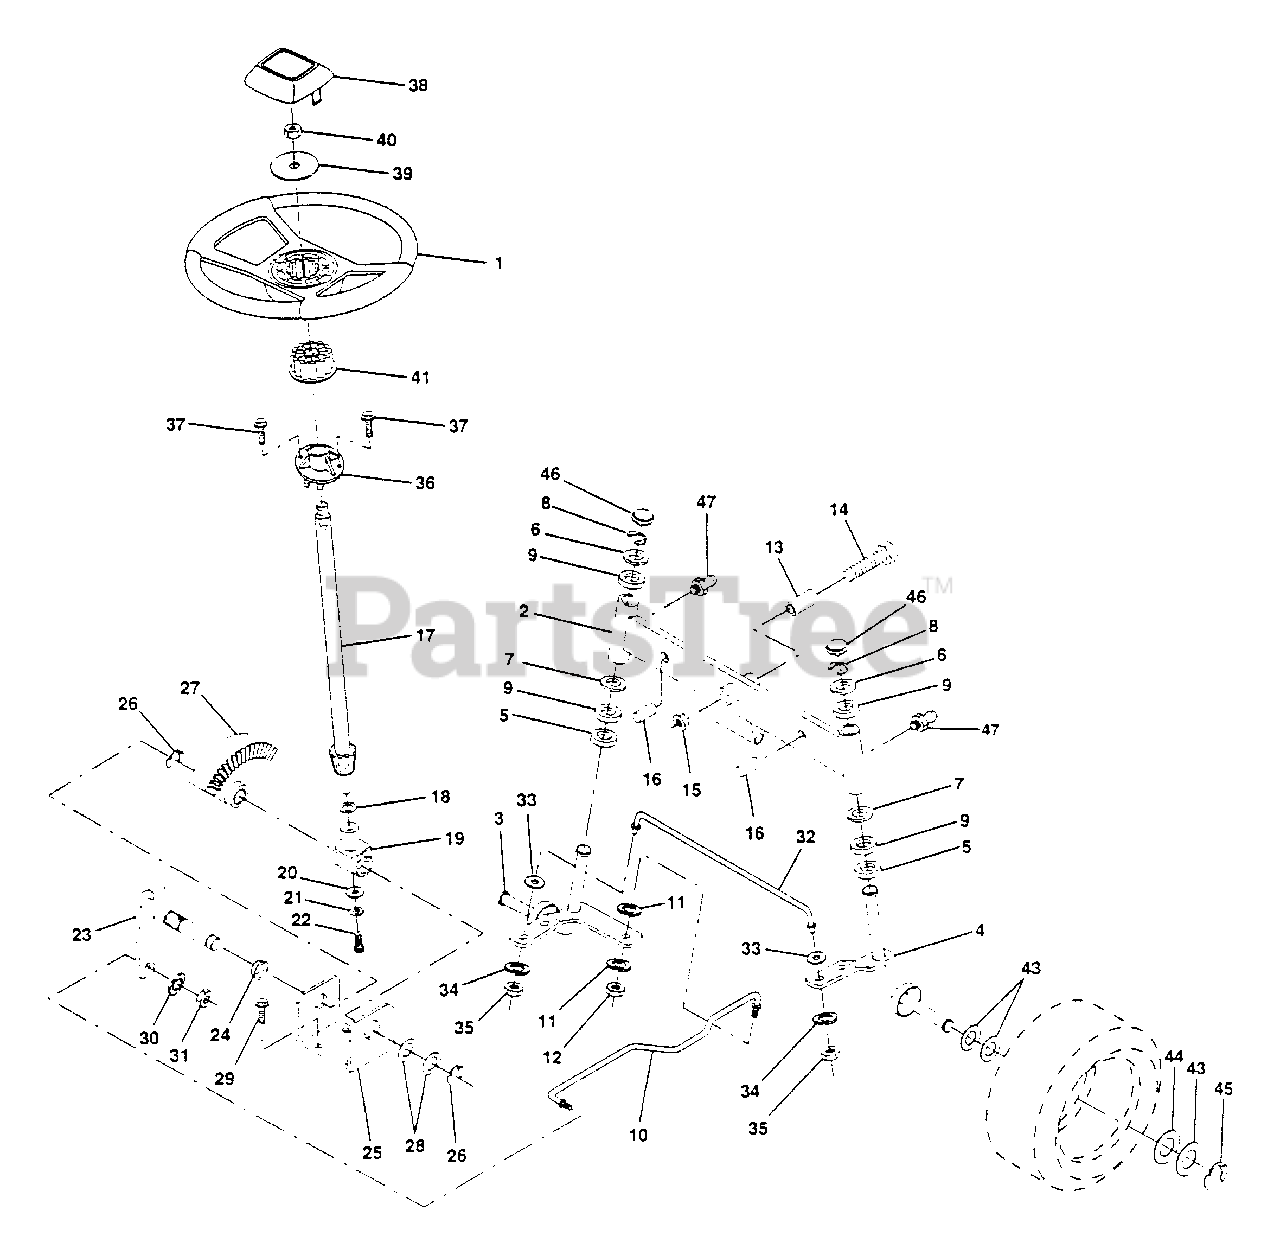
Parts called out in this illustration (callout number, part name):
1	Wheel Steering
2	Axle Asm Fr LT W/gzks 38/42
3	Spindle Asm LH
4	Spingle Asm RH
5	Bearing Race Thrust Harden
6	Washer 25/32 X 1-5/8 X 16 Ga
7	Washer 27/32 X 1-1/4 X 16 Ga
8	Ring Klip #t5304-75
9	Bearing Col Strg
10	Link Drag Sol Ball Jt
11	Washer Lock Hvy Hlcl Spr 3/8
12	Nut Fin 3/8-24 Unf
13	Spacer Bearing Axle Front
14	Bolt Hex 5/8-11 Unc X 3-1/2
15	Nut Lock Flange 5/8-11 Unc
16	Pin Axle 5/8 X 1 55/1 54 Lg
17	Shaft Asm Strg 18 31x3/4
18	Washer Thrust 515x 750x 033
19	Suport Shaft
20	Washer Shim 1/4 X 5/8 X 062
21	Washer Lock Hvy Helical 1/4
22	Screw Hex Socket 1/4-20 X 5/8
23	Shaft Asm Pittman
24	Nyliner Snap In
25	Bracket Steering
26	Ring Klip #t5304-75
27	Gear Sector
28	Bearing Race Thrust Harden
29	Screw Thdrol 3/8-16x3/4 Ty-tt
30	Washer Lock Hvy Hlcl 3/8
31	Nut Fin Hex 3/8-24 Unf
32	Rod Tie Wire Form
33	Washer 11/32 x 12/16 x 16 Ga.
34	Washer, Lock, Hvy Hlcl Spr 5/16
35	Locknut 5/16-24 Unf
36	Bushing Link Drag
37	Screw Slftp #10-16 X 1/2 Ty-b
38	Insert Cap Strg Wh Aut
39	Washer 53 X 2 25 X 160
40	Nut Hex Jam Taplock 1/2-20 Unf
41	Adapter Wheel Strg
43	Washer 25/32 X 1 1/4 X 16 Ja
44	Washer 25/32 X 1-5/8 X 16 Ja
45	Ring Klip #t5304-75
46	Cap Spindle Fr Top
47	Fitting Grease
